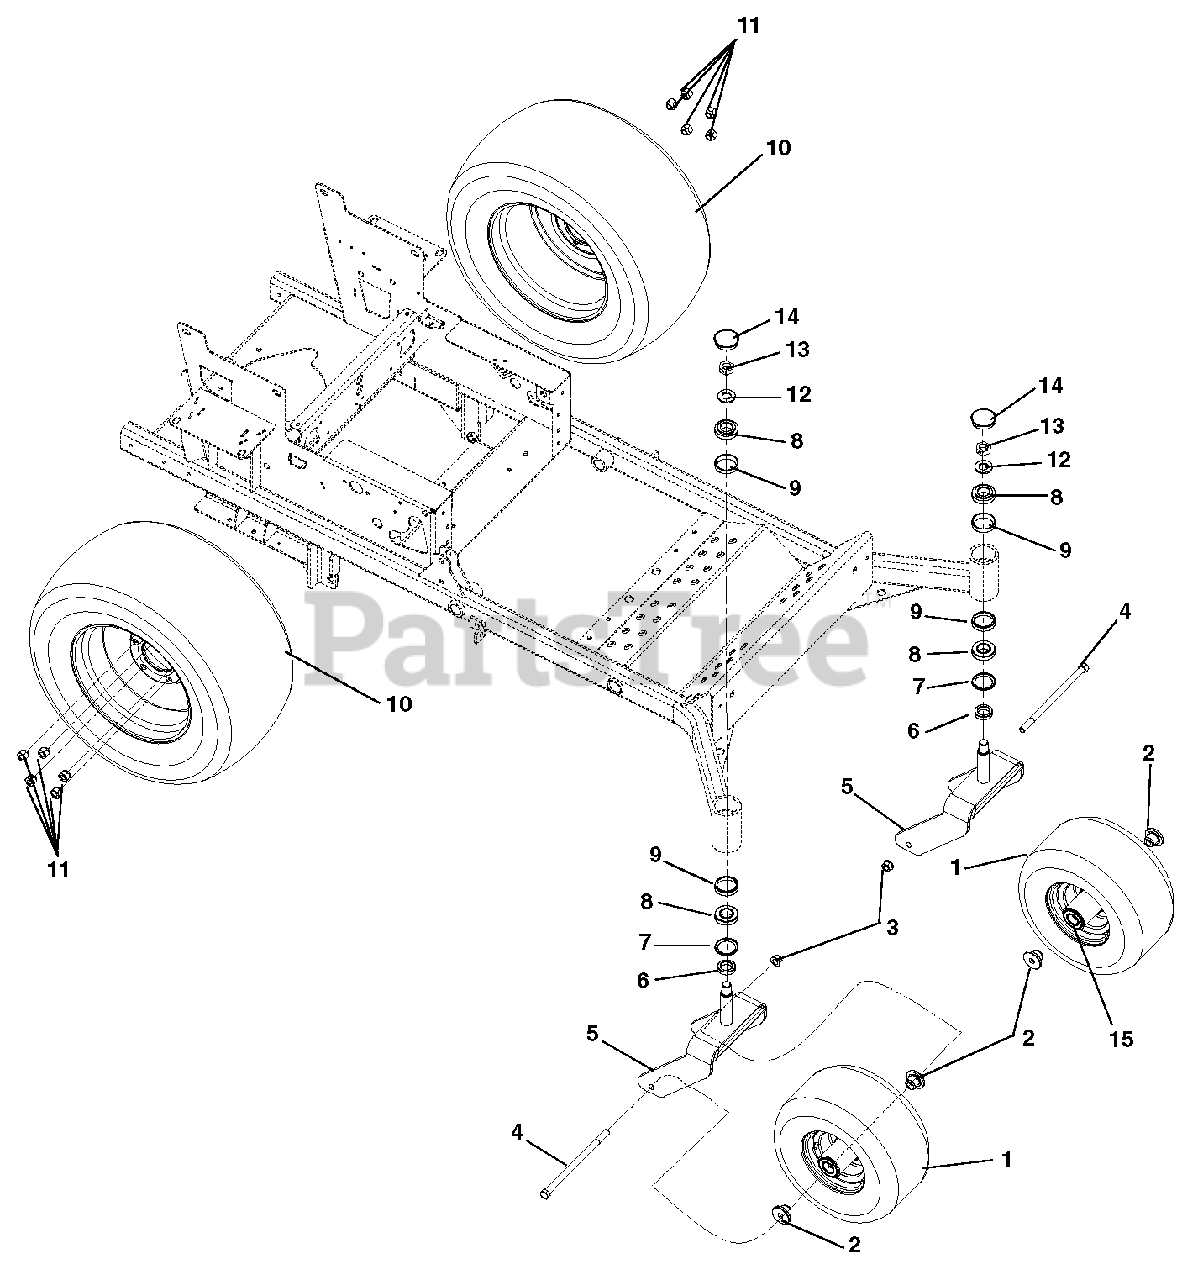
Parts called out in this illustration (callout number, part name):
1	Tire/Wheel Assembly, 13 x 6.50-6
2	Spacer, Front Wheel
3	Nut, .50-13 Nyloc Flange
4	Bolt, Hex .50-13 X 9.00 Grade 5
6	Spacer 1.258 x 1.75 x .550
7	Seal, Oil 1.75 x 2.332 x .312
8	Bearing, Cone 1.25 x .66
9	Bearing, Cup 2.328 x .465
10	Tire/Wheel Assembly, 23 x 10.00-12
11	Nut, Wheel .50-20 13/16 Across Flats Automotive Type
12	Washer, Flat Steel .812 x 2.00 x .148
13	Nut, Jam Center-Lock .75-16
14	Cap, Dust
15	Bearing, 25MM ID x 52MM OD x 15MM
